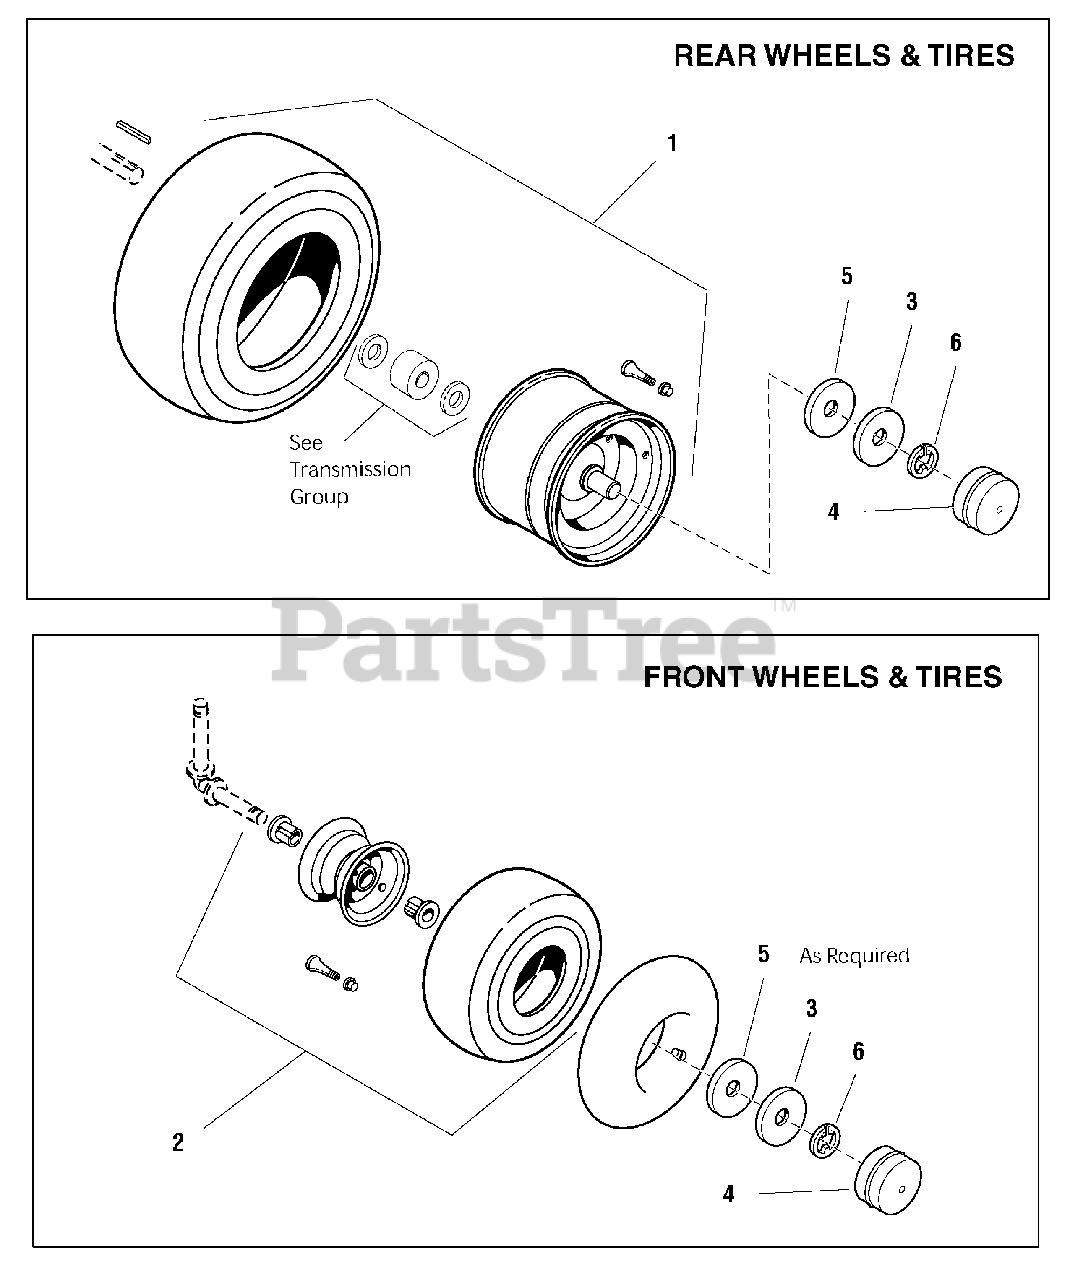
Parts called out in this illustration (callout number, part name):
1	WHEEL & TIRE ASSEMBLY, Rear 18 x 8-1/2-8
1	WHEEL & TIRE ASSEMBLY, Rear 20 x 8-8
2	WHEEL & TIRE ASSEMBLY, Front 15 x 6-6
2	WHEEL & TIRE ASSEMBLY, Front 15 x 6-1/2-6
3	WASHER, 3/4
5	WASHER, 3/4
